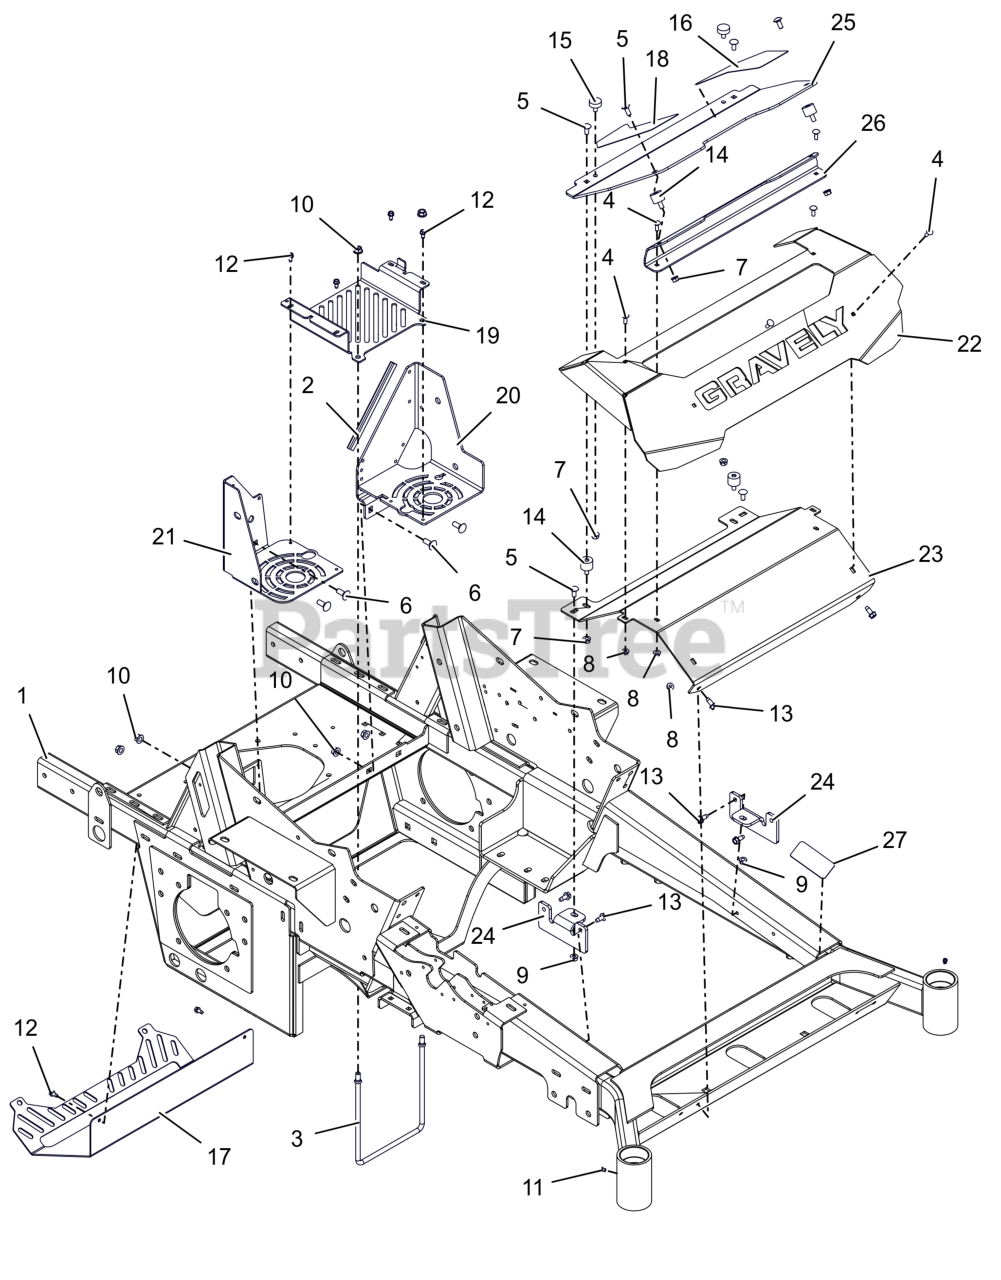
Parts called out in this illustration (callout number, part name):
1	WLDMT, 48", 52", 60" FRAME (RED)
2	STRIP, COWL
3	ROD, BRAKE MTG
4	BLT, RHSN .25-20X.750 G5 ZCC
5	BLT, RHSSN.31-18X.750 G5 ZCC
6	BLT, RHSN .38-16X1.00 G5 ZCC
7	NUT,SPNLK-FLG .31-18 G5 ZCC
8	NUT-LK-CTR-FLG .25-20 ZC120
9	NUT,LK-CTR-FLG .31-18 GF ZCC
10	NUT-LK-CTR-FLG .375-16 GF ZCC
11	FTG, .25-28 FLUSH MNT GREASE
12	SCR-TAP .25-20X.50 HWH ZCC
13	SCR,TAP .312-18X.75 HWH TR ZCC
14	BUMPER,STUD MNTD W/FEMALE INSR
15	BUMPER, RUBBER
16	KIT, PT300-600 ANTI-SKID Tape
17	GUARD, MUFFLER (BLACK)
18	KIT, PT300-600 ANTI-SKID Tape
19	TRAY- BATTERY
20	GUSSET-LH BATTERY TRY/ROPS-RED
21	GUSSET- FAN GUARD/ROPS - RED
22	BMPR-PT300-500 FRT FTRST/ -RED
23	BRKT-FRT BUMPER MTG/BACKER-BLK
24	BRKT- FOOTREST MTG
25	FOOTREST, PT300-500 (RED)
26	BRKT, FOOTREST SUPPORT (BLK)
27	KIT, PT300-600 ANTI-SKID Tape
